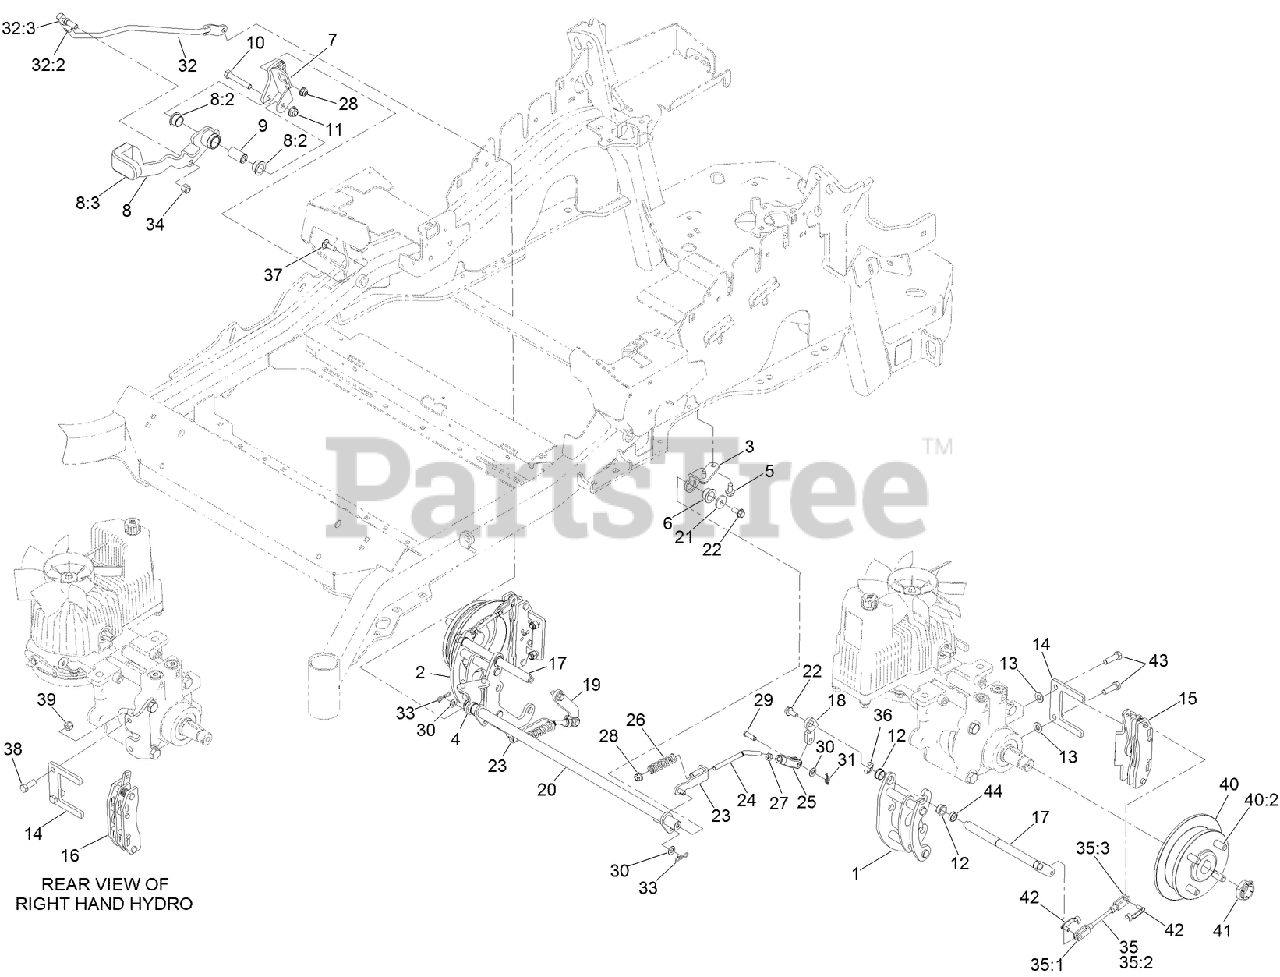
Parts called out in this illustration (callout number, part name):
1	MOUNT-BELLCRANK, LH
2	MOUNT-BELLCRANK, RH
3	MOUNT-PIVOT, LH
4	MOUNT-PIVOT, RH
5	SCREW-HWHTF
6	BUSHING-FLANGE
7	BRACKET-MOUNT
8	BRAKE LEVER ASM W/ GRIP
8:2	BUSHING-FLANGE
8:3	GRIP-LEVER
9	HANDLE-PIVOT, BRAKE
10	SCREW-HH
11	NUT-HF, NI
12	BUSHING
13	WASHER-FLAT
14	PLATE-MOUNT, BRAKE
15	CALIPER-BRAKE
16	CALIPER-BRAKE, RH
17	BELLCRANK
18	ARM-INNER, LH
19	ARM-INNER, RH
20	SHAFT-CROSS
21	WASHER-FLAT
22	SCREW-HHF
23	BRACKET-L
24	LINKAGE-MID
25	YOKE-OFFSET
26	SPRING-COMPRESSION
27	NUT-JAM
28	NUT-HF, NI
29	PIN-CLEVIS
30	WASHER-PLAIN
31	PIN-COTTER, LOCKING
32	FRONT LINKAGE ASM
32:2	END-TIE ROD, RH
32:3	NUT-HJ
33	PIN-COTTER, LOCKING
34	NUT-LOCK
35	REAR LINKAGE ASM
35:2	LINKAGE, REAR
35:3	NUT-JAM
36	E-RING
37	BOLT-CARR
38	SCREW-HH
39	NUT-LOCK, NI
40	WHEEL HUB ASM
40:2	STUD-WHEEL
41	LOCKNUT
42	PIN-CLEVIS, SPRING
43	SCREW-LOCK, PATCH
44	SPACER
